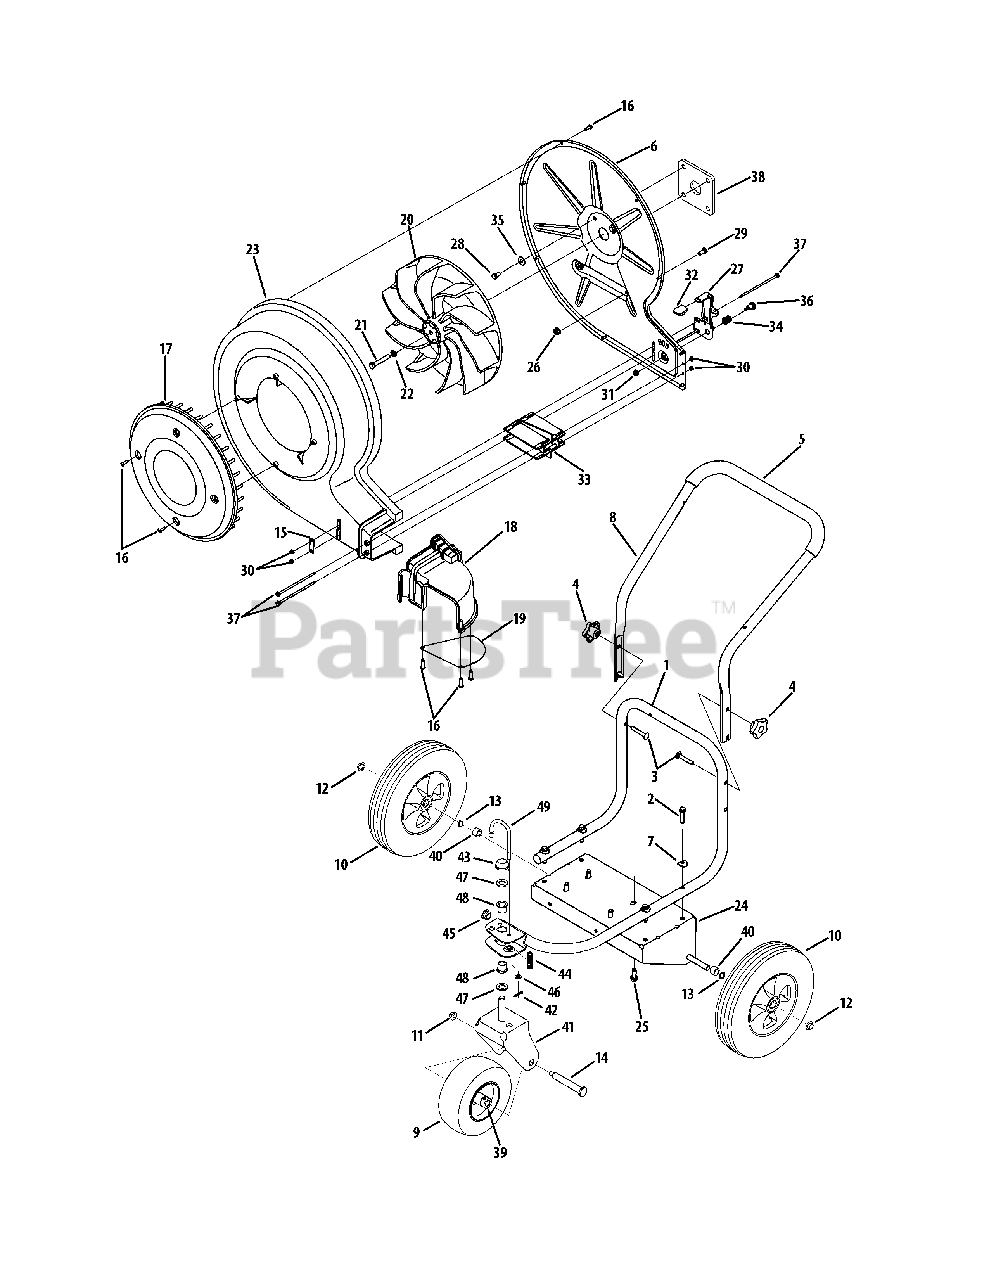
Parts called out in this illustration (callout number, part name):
1	Lower Handle Assembly
2	Hex Screw, 5/16-18 x 1.50
3	Carriage Screw, 5/16-18 x 2.00
4	Star Knob, 5/16-18
5	Foam Grip, .970 x 25
6	Back Plate
7	Saddle Washer, .320 x .93 x .060
9	Wheel, 8 x 3
10	Wheel, 12 x 3, Beige
11	Flange Lock Nut, 3/8-16
12	Push Cap, 1/2"
13	Wave Washer, .510 x .750 x .017
14	Shoulder Screw, .625 x 3.94
16	Hex Screw, 12-16 x .75
17	Blower Cover
18	Chute Assembly
20	Impeler Assembly
21	Hex Screw, 3/8-24 x 2.25
22	Lock Washer, 3/8
23	Blower Housing
25	Sems Screw, 3/8-16 x 1.000
26	Flange Lock Nut, 5/16-18
27	Louver Lever
28	Hex Bolt, 5/16-24 x 1.00
29	Hex Bolt, 5/16-18 x .75
30	Hex Lock Nut, #8-32
31	Flange Lock Nut, 1/4-20
32	Height Adjustment Knob
33	Louver Plate
34	Comp. Spring, .515 x .641 x .95
35	Bell Washer, .340 x .872 x .060
36	Shoulder Screw, .437 x .50 x 1/4-20
37	Shoulder Screw, .18 x 4.8 x 8-32
39	Flange Bearing w/ Fitting
40	Spacer, .525 x .775 x .560
41	Caster Wheel Bracket Assembly
42	Cotter Pin
44	Compr. Sprng., .531 OD x 1.75 Lg
46	Washer, Flat, .330 x .630 x .0635
47	Washer, Flat, .640 x 1.12 x .125
48	Flange Bearing, .631 ID
